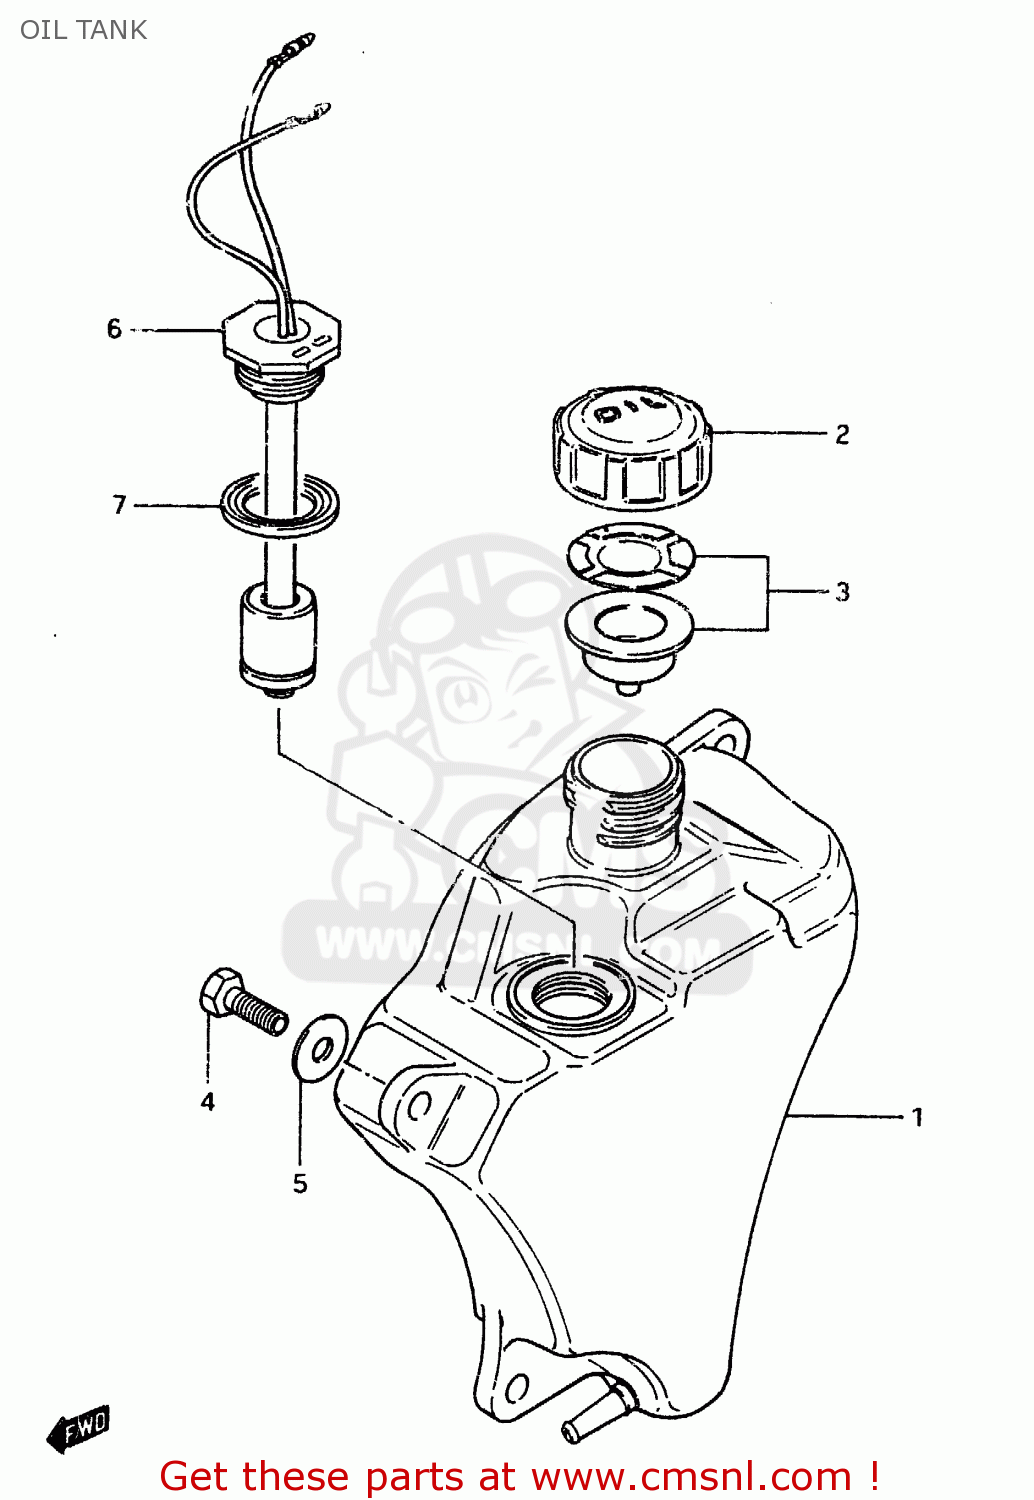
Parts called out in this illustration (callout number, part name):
1	TANK, OIL
2	CAP,OIL TANK
3	GASKET SET (NAS)
4	BOLT, UPPER
5	WASHER
6	SWITCH, OIL LEVEL
7	GASKET (NAS)
